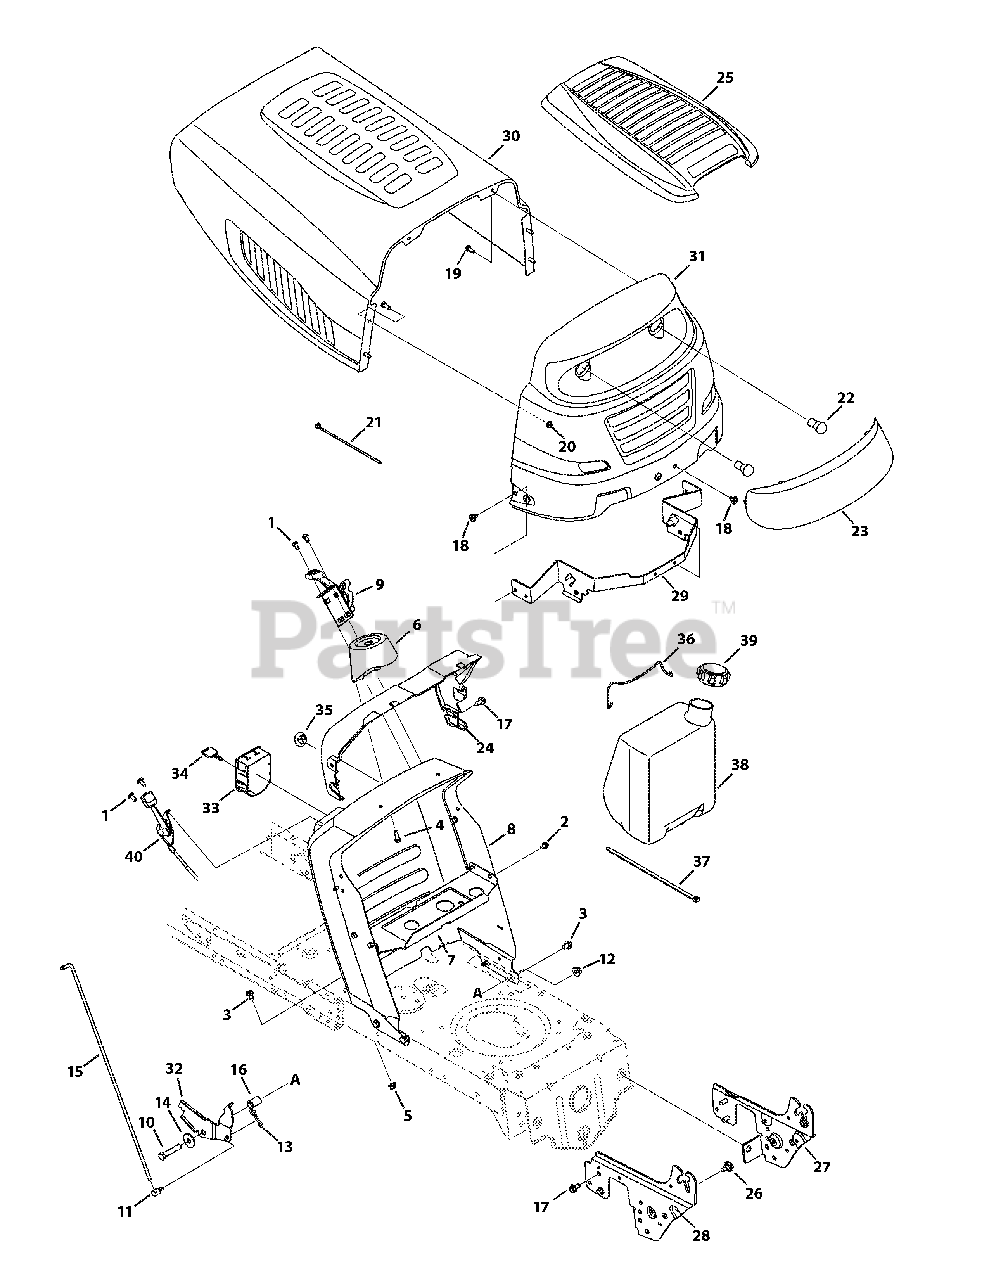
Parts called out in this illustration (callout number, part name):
1	Screw, 1/4-20 x .500
2	Hex Index Washer Screw, 1/4-20 x .500
3	Screw, 5/16-18 x .625
4	Screw, 1/4-15 x .750
5	Flangelock Nut, 5/16-18
6	Steering Support
7	Gas Tank Support Bracket
8	Dash, No RMC
9	7-speed Control Assembly
10	Hex Screw, 3/8-16 x 2.0
11	Ferrule, 1/4-20 x 1.0
12	Flangelock Nut, 3/8-16
13	Bow Tie Cotter Pin, 72
14	Flat Washer, .411 x 1.25 x .100
15	Speed Selector Control Rod
16	Flange Spacer, .390 x .671 x 1.095
17	Screw, 5/16-18 x .750
18	Screw, 5/16-18 x .375
19	Hex Screw, 1/4-20 x .620
20	Flangelock Nut, 1/4-20
21	Cable Tie
22	Miniature Lamp, 12V
23	Grill Lens
24	Dash Collar
25	Hood Cover
26	Shoulder Screw, 5/16-18, .43 x .29
27	Left-hand Support Pivot Bracket
28	Right-hand Support Pivot Bracket
29	Hood Pivot Bracket
31	Grill
33	Key Switch
35	Choke Plug
36	Battery Rod
37	Cable Tie
38	Fuel Tank, 1.5 Gallon
39	Fuel Cap
40	Throttle/Choke Cable
